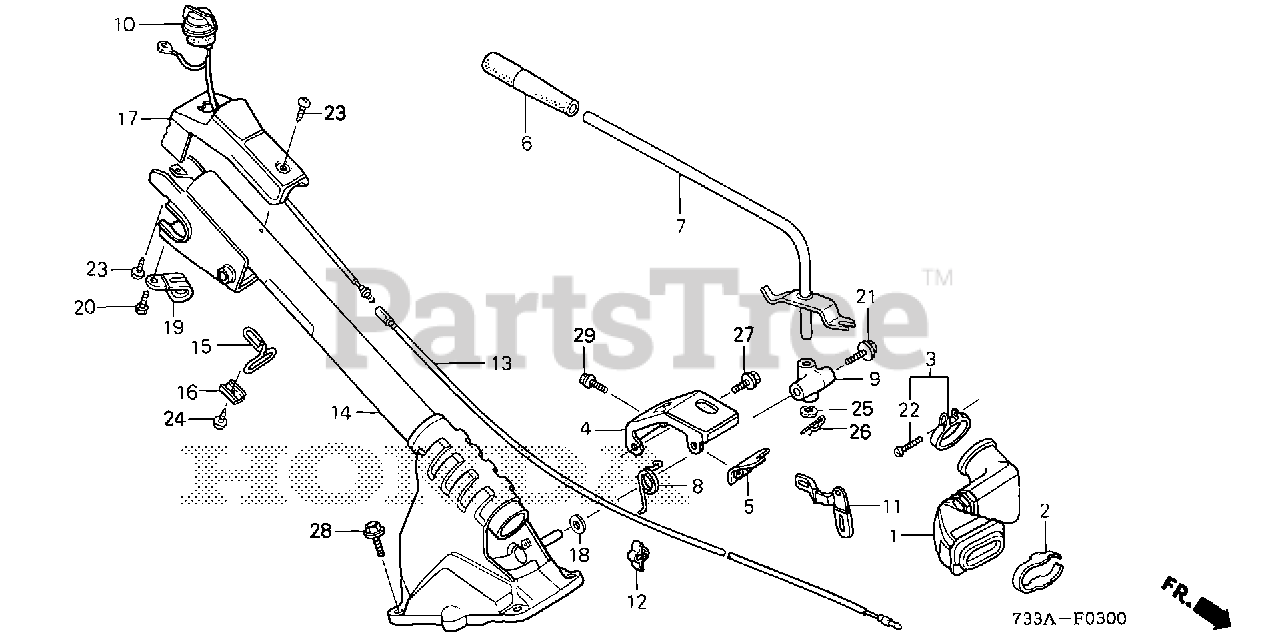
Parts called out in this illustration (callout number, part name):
1	HOSE, AIR CLEANER
2	CLIP, AIR CLEANER HOSE
3	BAND ASSY., AIR CLEANER HOSE
4	COVER, CHANGE
5	PLATE, CHANGE STOPPER
6	GRIP, AUXILIARY CHANGE LEVER
7	LEVER, CHANGE
8	SPRING, CHANGE LEVER RETURN
9	HOLDER, CHANGE LEVER
10	SWITCH ASSY., ENGINE STOP
12	HOLDER, STOP SWITCH WIRE
13	WIRE, ENGINE STOP
14	COLUMN, HANDLE *R280* (POWER RED)
15	GUIDE, CABLE
17	COVER, HANDLE COLUMN
18	WASHER (10X24)
19	CLIP, WIRE HARNESS (6.3MM)
20	BOLT, HEX. (5X14)
21	BOLT-WASHER (6X12)
22	SCREW, PAN (4X30)
23	SCREW, TAPPING (5X12)
24	SCREW, TAPPING (5X10)
25	WASHER, PLAIN (10MM)
26	PIN, LOCK (10MM)
27	BOLT, FLANGE (6X10)
28	BOLT, FLANGE (8X16)
29	BOLT, FLANGE (6X10)
